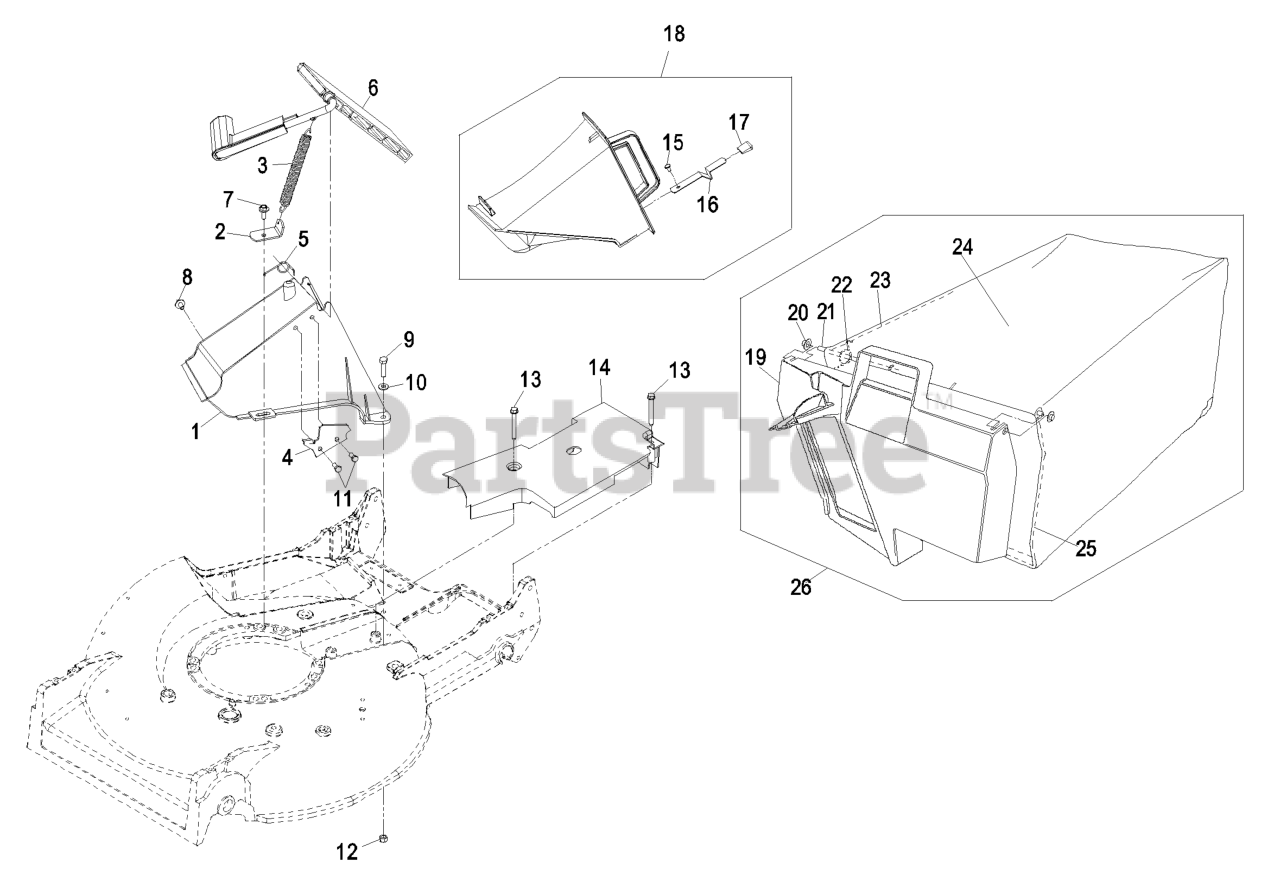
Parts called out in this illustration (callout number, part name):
1	TUNNEL-DISCHARGE
2	BRACKET-SPRING
3	SPRING-DOOR
4	LATCH-PLATE
5	RETAINER-DOOR
6	DISCHARGE DOOR ASM
7	SCREW-HWH
8	SCREW AND WASHER ASM
9	SCREW-HH
10	WASHER-FLAT
11	SCREW-PLASTITE
12	NUT-LOCK, NI
13	SCREW-HWH
14	COVER-BELT
15	RIVET-HEAD, FLAT
16	LATCH-PLUG, DISCHARGE
17	GRIP-LATCH
18	DISCHARGE PLUG ASM
20	NUT-PUSH
21	HINGE-DOOR, BAG
24	BAG, GRASS METRO21
25	FRAME-BAG
26	ASM,GRASS BAG
